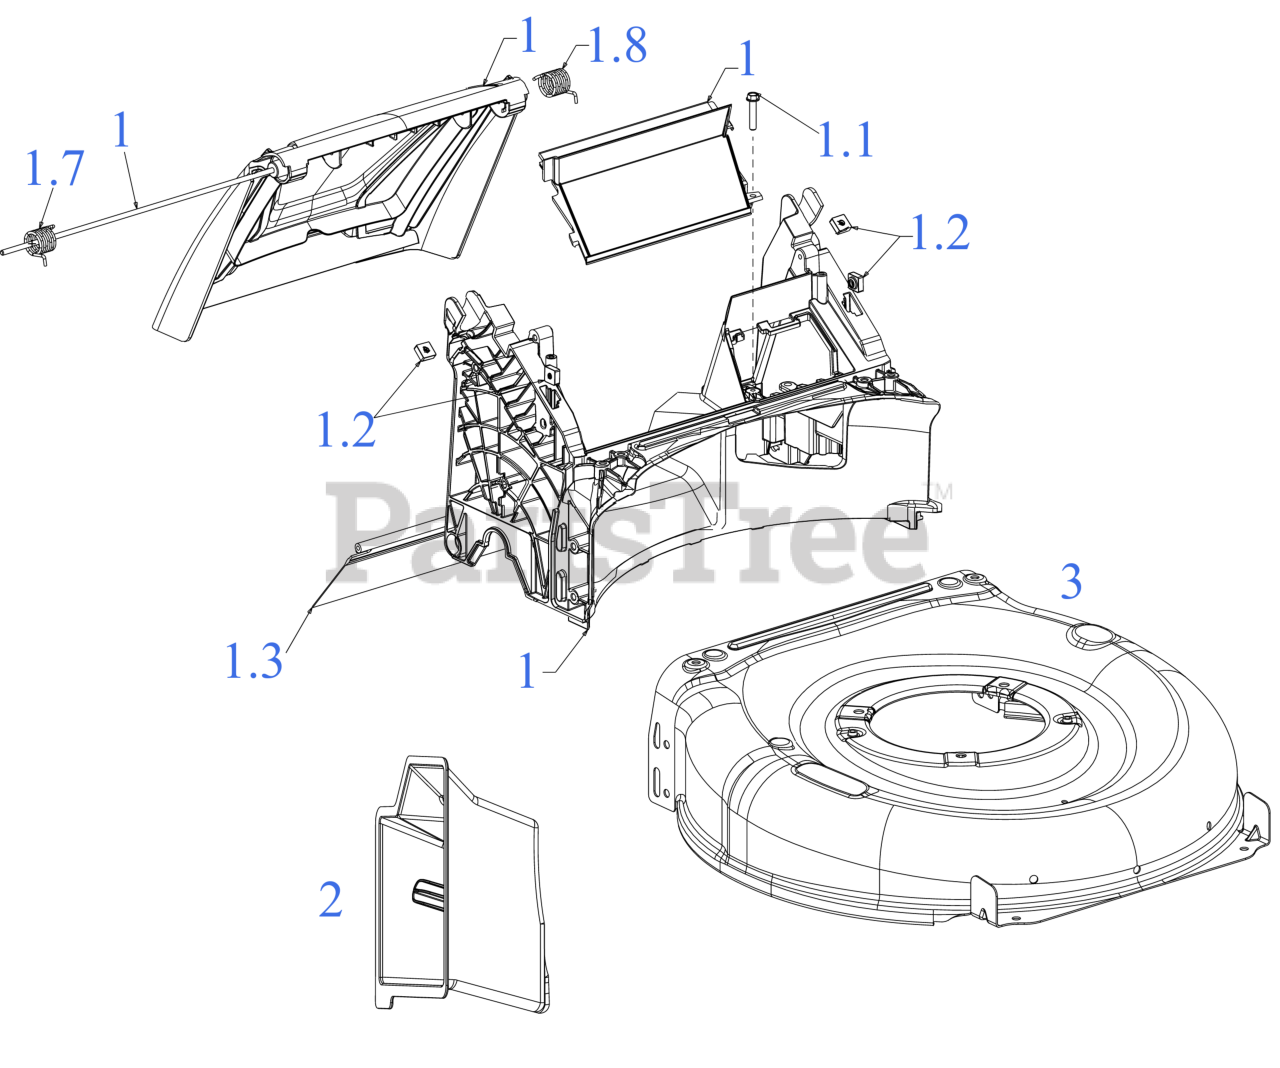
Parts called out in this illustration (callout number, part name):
1	REAR BAFFLE
1.1	SCREW 1/4-15 x 1.250
1.2	SQUARE LOCK NUT 1/4X20
1.3	TRAILSHIELD
1.7	TORSION SPRING (RH)
1.8	TORSION SPRING (LH)
2	MULCH PLUG
